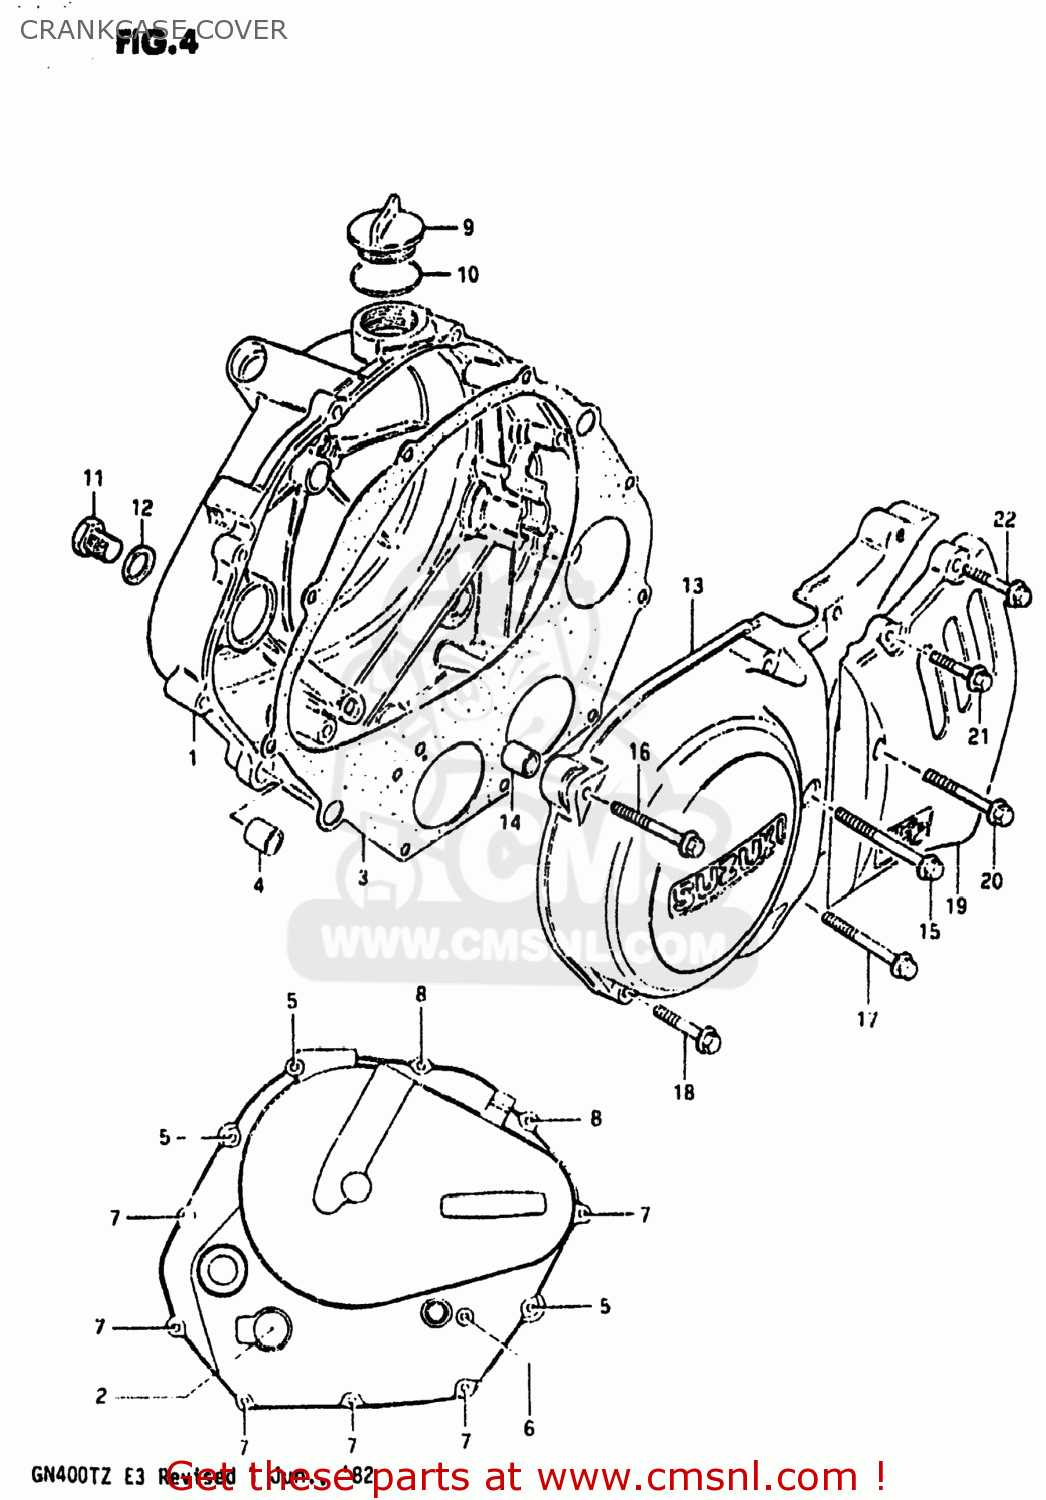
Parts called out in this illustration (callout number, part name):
1	COVER,CLUTCH
2	LENS,OIL LEVEL CHECK
3	GASKET,CLUTCH COVER (MCA)
4	PIN
5	BOLT (6X50)
6	BOLT (6X40)
7	BOLT (6X35)
8	BOLT
9	CAP
10	O RING(D:2.2,ID:32)
11	PLUG (14X12)
12	GASKET(14X19.2X2) (NAS)
13	COVER,MAGNETO
14	PIN
15	BOLT
16	BOLT (6X50)
17	BOLT
18	BOLT (6X35)
19	COVER,ENGINE SPROCKET
20	BOLT (6X40)
21	BOLT
22	BOLT (6X20)
